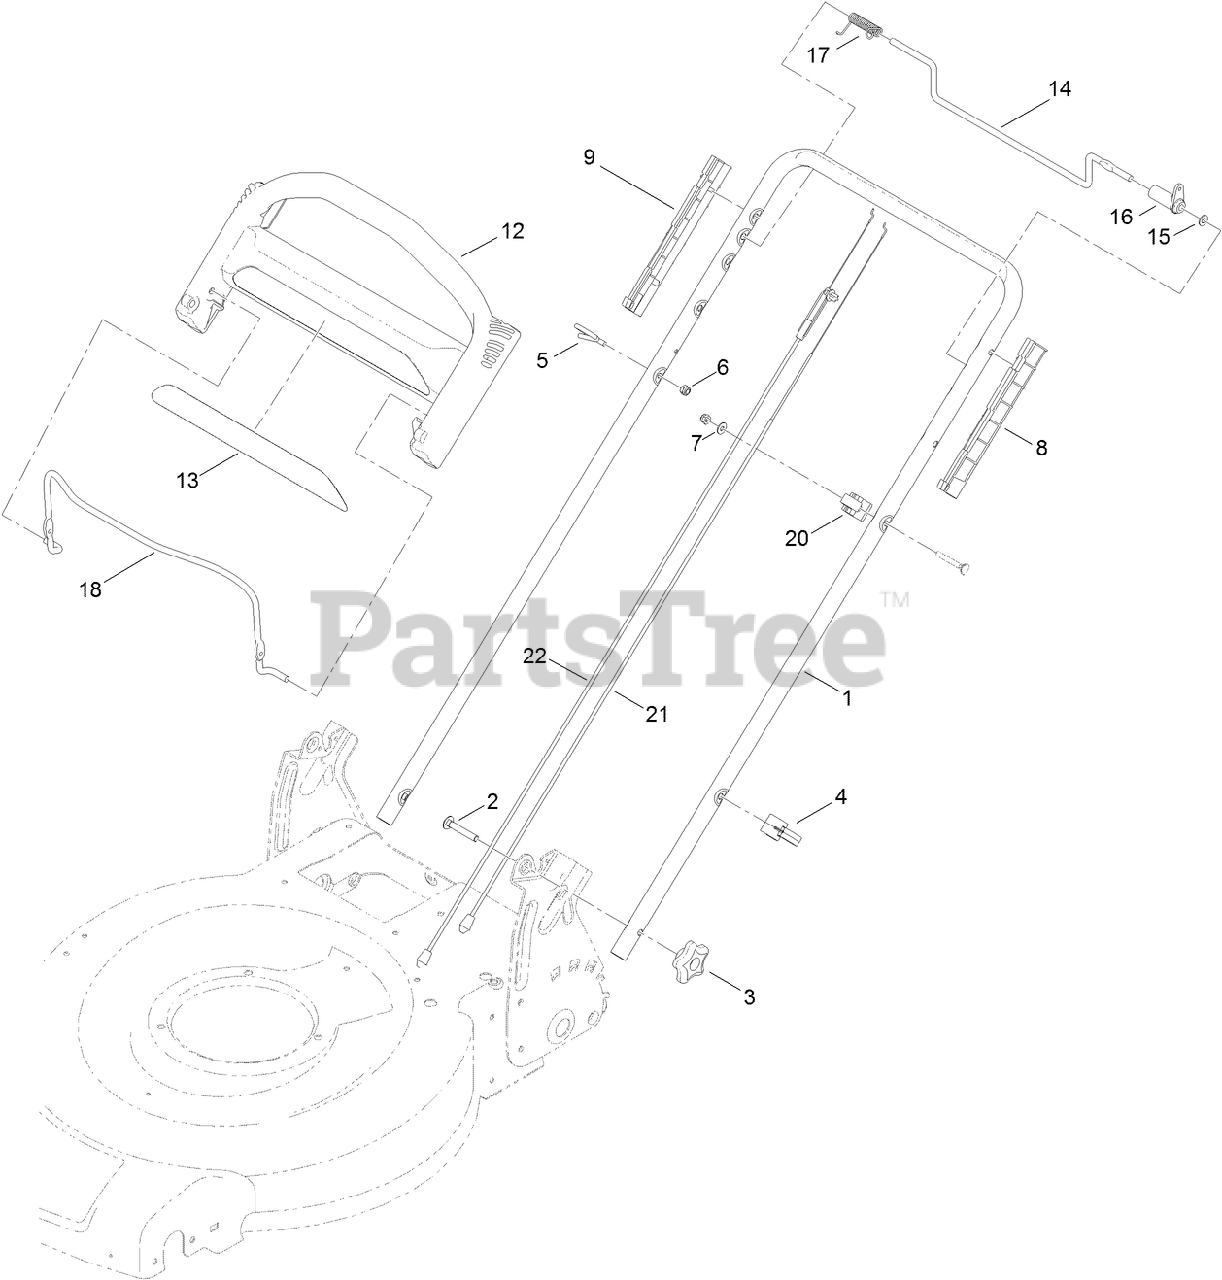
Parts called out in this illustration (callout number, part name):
2	BOLT-CARR
3	KNOB-HANDLE
4	GUIDE-CABLE
5	GUIDE-ROPE
6	NUT-LOCK, NI
7	WASHER-FLAT
8	GUIDE-LH
9	GUIDE-RH
12	HANDLE-CONTROL
15	WASHER-PLAIN
16	LEVER-TRACTION
21	CABLE-TRACTION
22	CABLE-BRAKE
